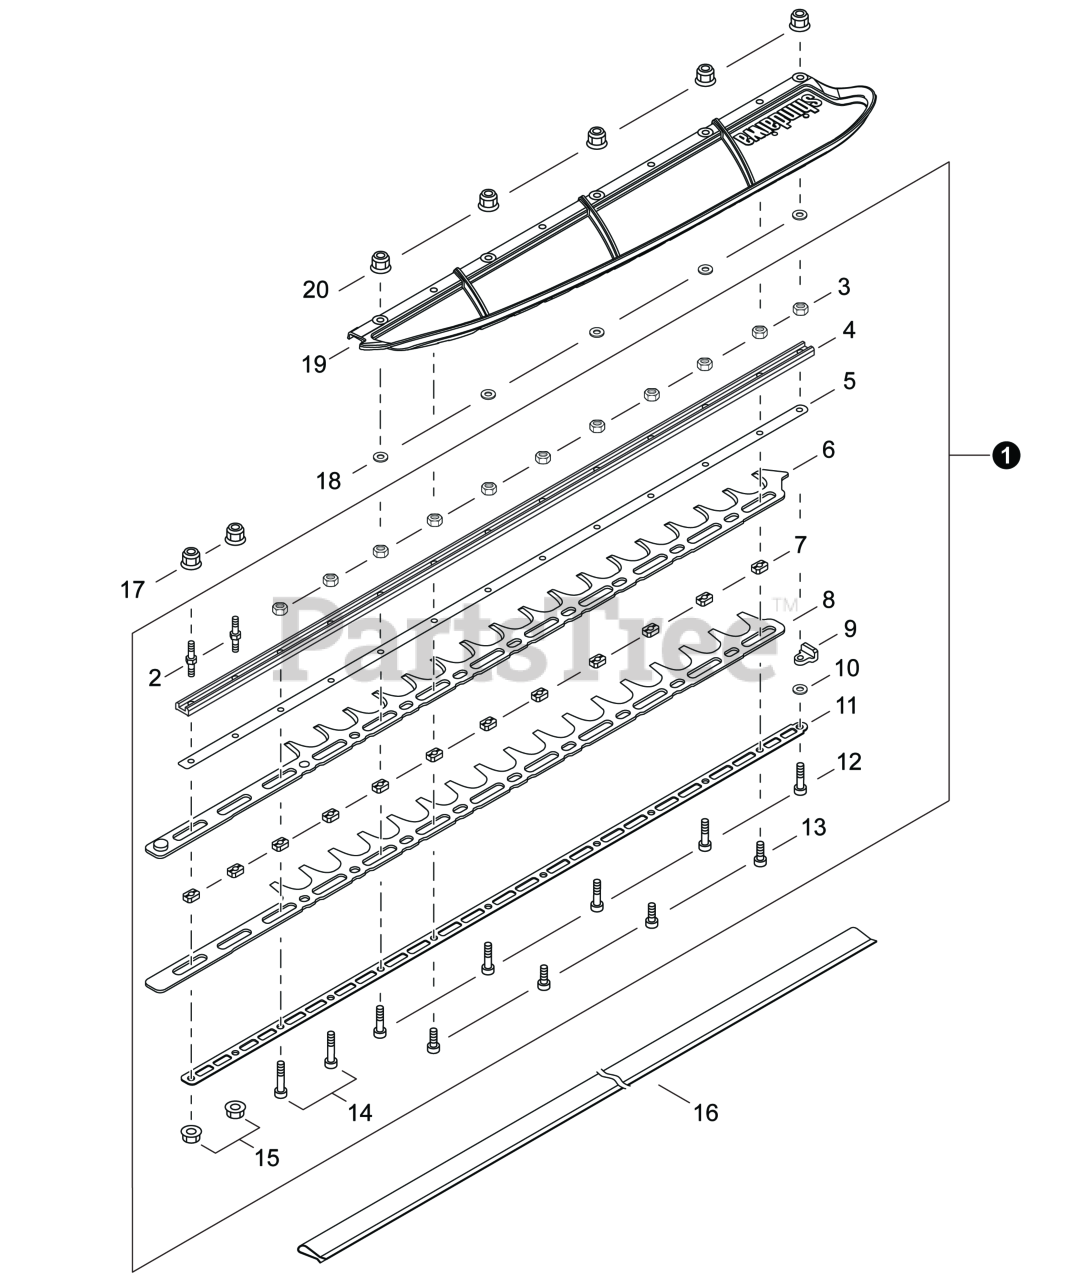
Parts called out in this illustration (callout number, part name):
1	CUTTER ASSY, 37.6"
2	STUD, MOUNTING M5×36
4	SUPPORT, BLADE 37.6"
5	SUPPORT, BLADE 37.6"
6	BLADE - UPPER - 37.6"
8	BLADE - LOWER - 37.6"
11	SUPPORT, BLADE 37.6"
12	BOLT, TORX 5×25
13	BOLT, TORX 5×16
14	BOLT, TORX 5×30
15	NUT, FLANGE M5
16	SCABBARD
17	NUT, FLANGE M5
18	WASHER, FLAT 5.5×10×0.8
19	DEFLECTOR, DEBRIS
20	NUT, FLANGE M5
